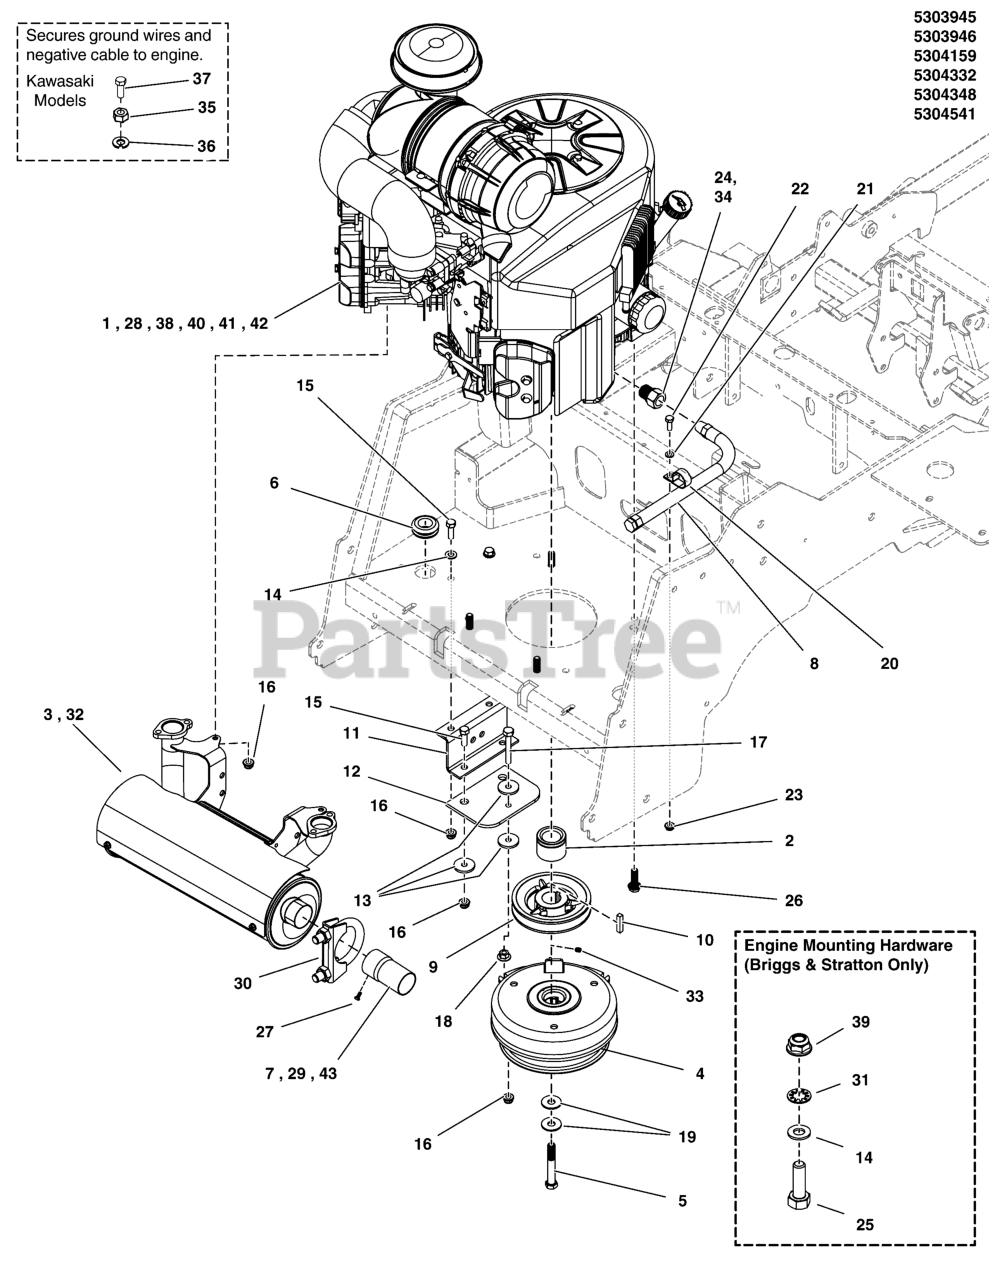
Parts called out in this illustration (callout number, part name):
1	ENGINE, KAWA, DFI
2	SPACER, 1.13 X 1.75 X 1.35, CZ
3	MUFFLER 37 HP KAWASAKI
4	CLUTCH, WARNER, 250 ft lbs - 1.13"
5	BOLT, CRANKSHAFT, 7/16-20 X 3-1/4, GD 8
6	GROMMET, 7/8"ID, 1/4" THICK STK
7	EXTENSION, TAILPIPE, 3"
8	HOSE, OIL DRAIN
9	PULLEY, 4.75 OD X 1-1/8 BORE, BC-48
10	KEY, 1/4" SQ. X 1-1/4
11	ANCHOR, CLUTCH, IS600-IS700 - BLK
12	CLUTCH ANCHOR PAD
13	WASHER, .34 X 1.25 X 10 GA
14	WASHER, 5/16" SAE
15	BOLT, 5/16-18 X 1" GRD5 YZ
16	NUT, 5/16-18 HEX NYLOCK FLANGE NUT
17	BOLT, 5/16-18 X 2-1/4 TFL, GD5 YZ
18	NUT, 5/16-18 HEX SERRATED FLANGE (LARGE)
19	BELLEVILLE WASHER, 1.1875 X .442 X .098
20	CLAMP, VINYL INSULATED, 1.00
21	WASHER, 1/4 SAE
22	BOLT, 1/4"-20 X 3/4" GD5 YZ
23	NUT, 1/4-20 HEX SERR. FLANGE
24	ADAPTER, Oil Drain
25	BOLT, 5/16-24 X 1-3/4, GD8, PHOS
26	BOLT, HEX FLG, SER, GD5 3/8-16 X 1-1/4" PACH CZ
27	SCREW, SELF-TAP, #8-32 X 3/8. WASH HEX, CZ
28	ENGINE, B&S, VANGUARD
29	TAIL PIPE EXTENTION, 1.78"ID X 5" LG
30	CLAMP, TAILPIPE, 1-7/8"
31	WASHER, 5/16" Internal Tooth Lock
32	MUFFLER (Purchase from Engine Manufacturer)
33	SET SCREW, 5/16-18 X 3/8, KNURL, W/PATCH
34	METRIC ADAPTER, M14-1.5" TO 3/8 NPTF
35	NUT, HEX, M8-1.25, CZ, GD 8.8
36	WASHER, 5/16 LOCK CZ
37	BOLT, M8-1.25 X 20 MM GD 8.8
39	NUT, 5/16-24, TOP LOCK FLANGE, GD8 PHOS
40	ENGINE, 32, B&S, 543777-2120-J1
41	ENGINE, 35, KAWASAKI
42	ENGINE, 28HP BRIGGS VANGUARD, EFI
43	EXTENSION, TAILPIPE, 3" - BLACK
